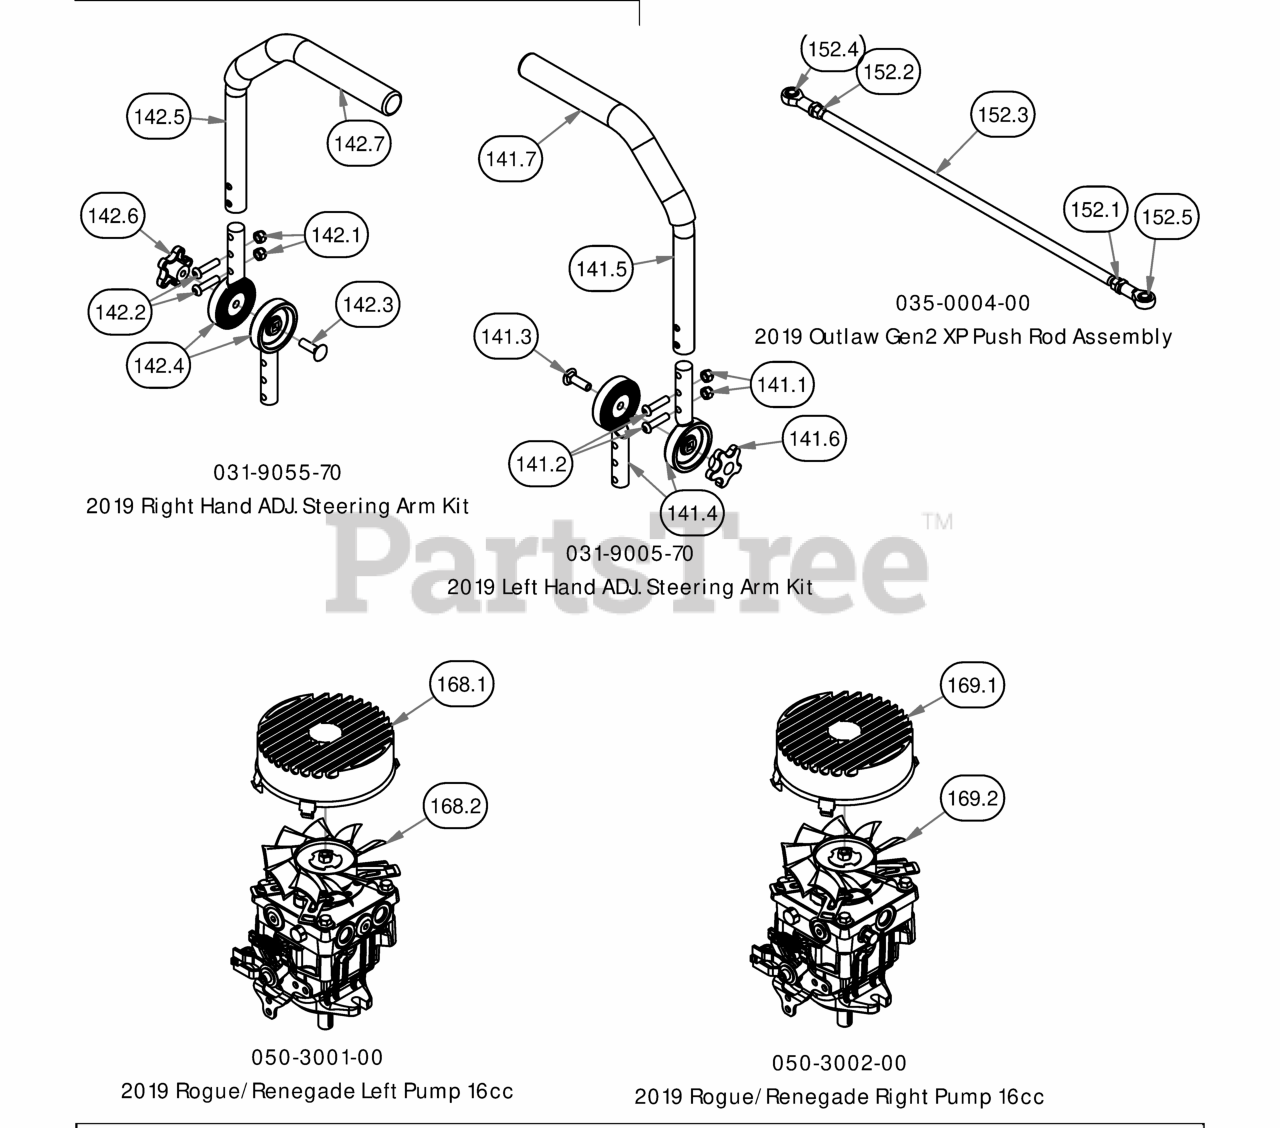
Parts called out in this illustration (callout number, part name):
141.1	5/16-18 Nylock Insert Locknut
141.2	5/16-18 UNC X 1-3/8" BHCS, TORX DRIVE, GR 5
141.3	3/8" x 1 1/4" Carriage Bolt
141.4	2019 Steering Arm Adjuster Casting
141.5	2019 Steering Arm Grip
141.6	Black Knob for Adjustable Steering Arm
141.7	Black Steering Arm Grip
142.1	5/16-18 Nylock Insert Locknut
142.2	5/16-18 UNC X 1-3/8" BHCS, TORX DRIVE, GR 5
142.3	3/8" x 1 1/4" Carriage Bolt
142.4	2019 Steering Arm Adjuster Casting
142.5	2019 Steering Arm Grip
142.6	Black Knob for Adjustable Steering Arm
142.7	Black Steering Arm Grip
152.1	5/16" RH Fine Threaded Jam Nut
152.2	5/16" LH Fine Threaded Jam Nut
152.3	2019 Outlaw Gen2 Xp Rod
152.4	Spherical Rod End - Outlaw
152.5	Spherical Rod End - Outlaw
168.1	Fan Guard 6" Fits wheel Motor Pumps
168.2	Hydraulic Fan
169.1	Fan Guard 6" Fits wheel Motor Pumps
169.2	Hydraulic Fan
